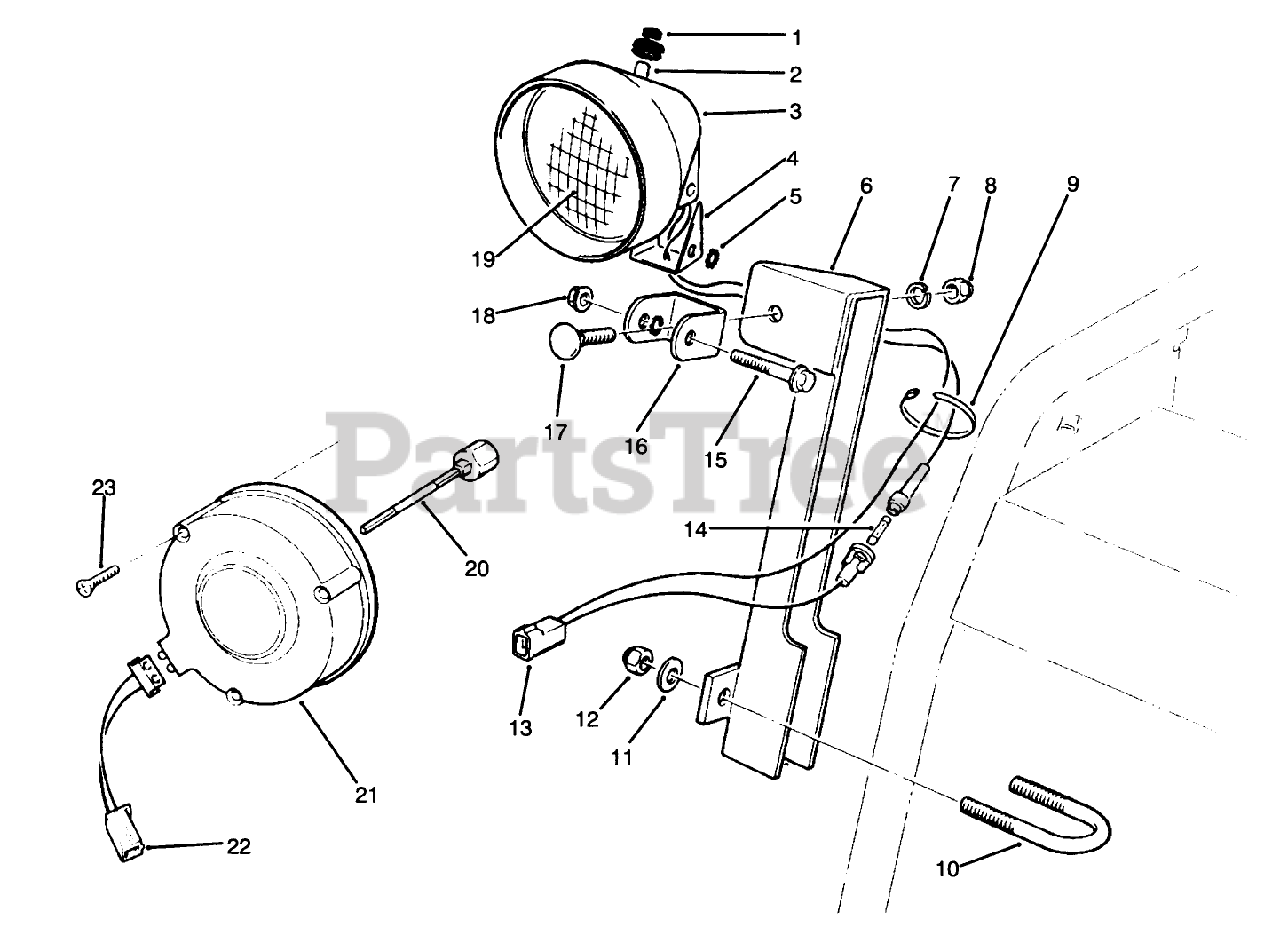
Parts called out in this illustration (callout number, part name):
1	BOOT-SWITCH
2	SWITCH ASM
3	Bucket-Headlamp
4	TO BE DISCONTINED-NOT NEEDED ON PRODUCT
5	WASHER-LOCK
6	Mount-Lamp
7	WASHER-LOCK
8	NUT-HEX
9	TIE-CABLE
10	U-BOLT
11	WASHER-PLAIN
12	NUT-LOCK, NI
13	Wire Assembly
14	Fuse-7-1/2 Amp.
15	SCREW-HH
16	BRACKET
17	BOLT-CARR
18	NUT-HF
19	BEAM-SEALED
20	Shaft-Alternator, 3 Inch
21	Alternator
22	Connector-Wire
23	SELF TAP SCREW
